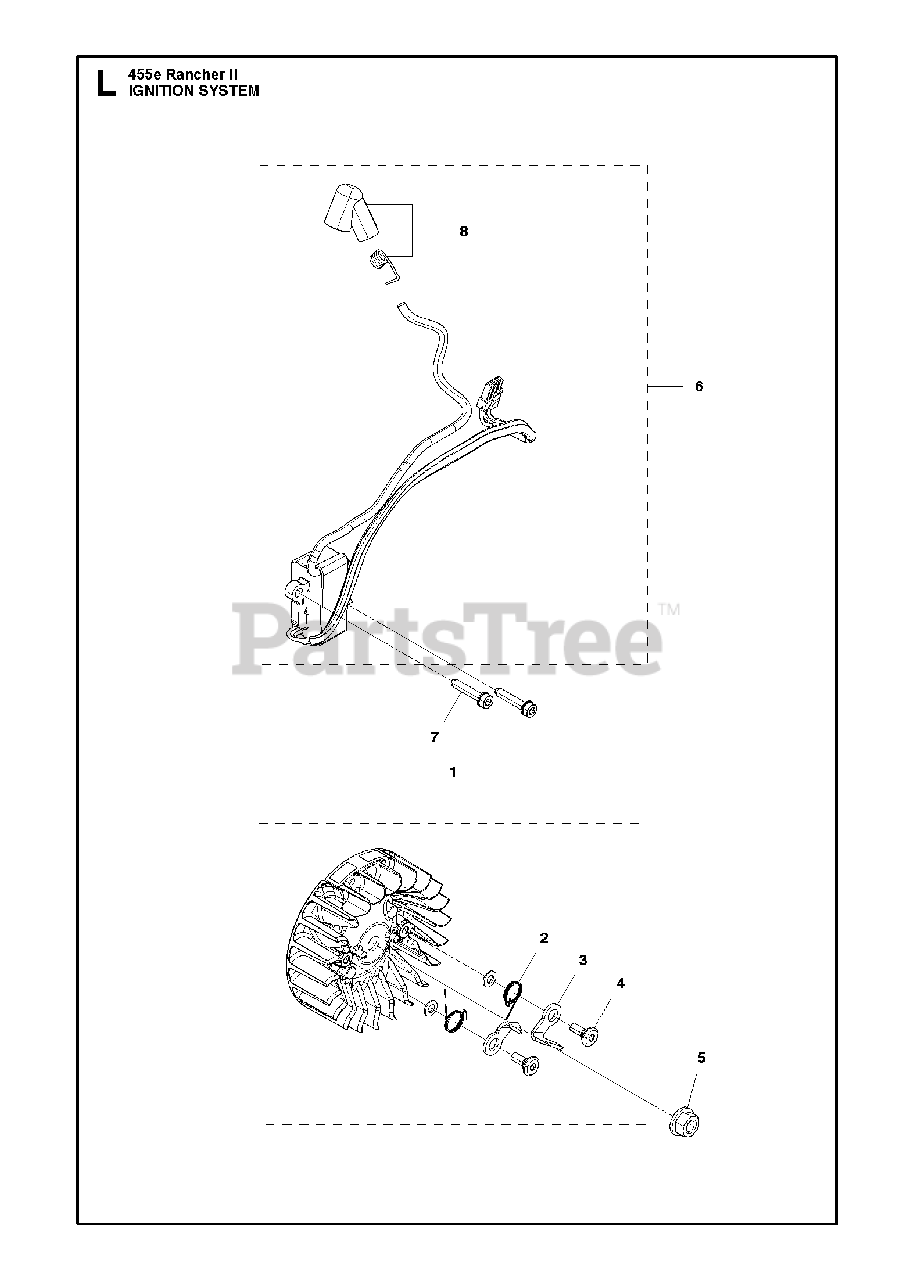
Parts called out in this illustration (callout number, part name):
1	FLYWHEEL ASSY
2	SPRING
3	PAWL
4	SCREW
5	NUT W/ WASHER
6	IGNITION MODULE
7	SCREW
8	SPARK PLUG CAP ASSY
